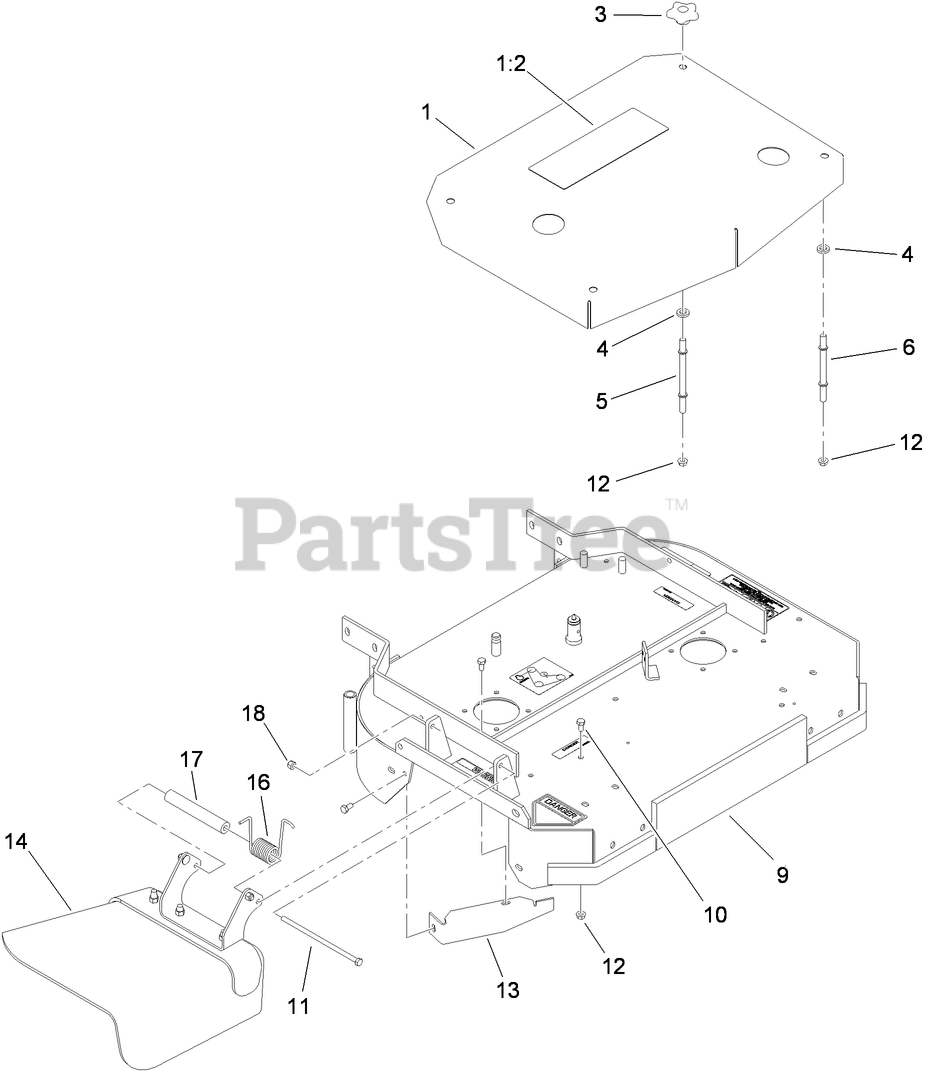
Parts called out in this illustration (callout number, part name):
1	SHIELD-BELT
3	KNOB-HANDLE
4	WASHER
5	STUD-SHIELD, BELT (LONG)
6	STUD-SHIELD, BELT (SHORT)
9	32 INCH DECK ASM
10	SCREW-HH
11	SCREW-HH
12	NUT-HF
13	BAFFLE-DOGLEG
14	DEFLECTOR ASM
16	SPRING-TORSION
17	SPACER
18	NUT-LOCK, NI
